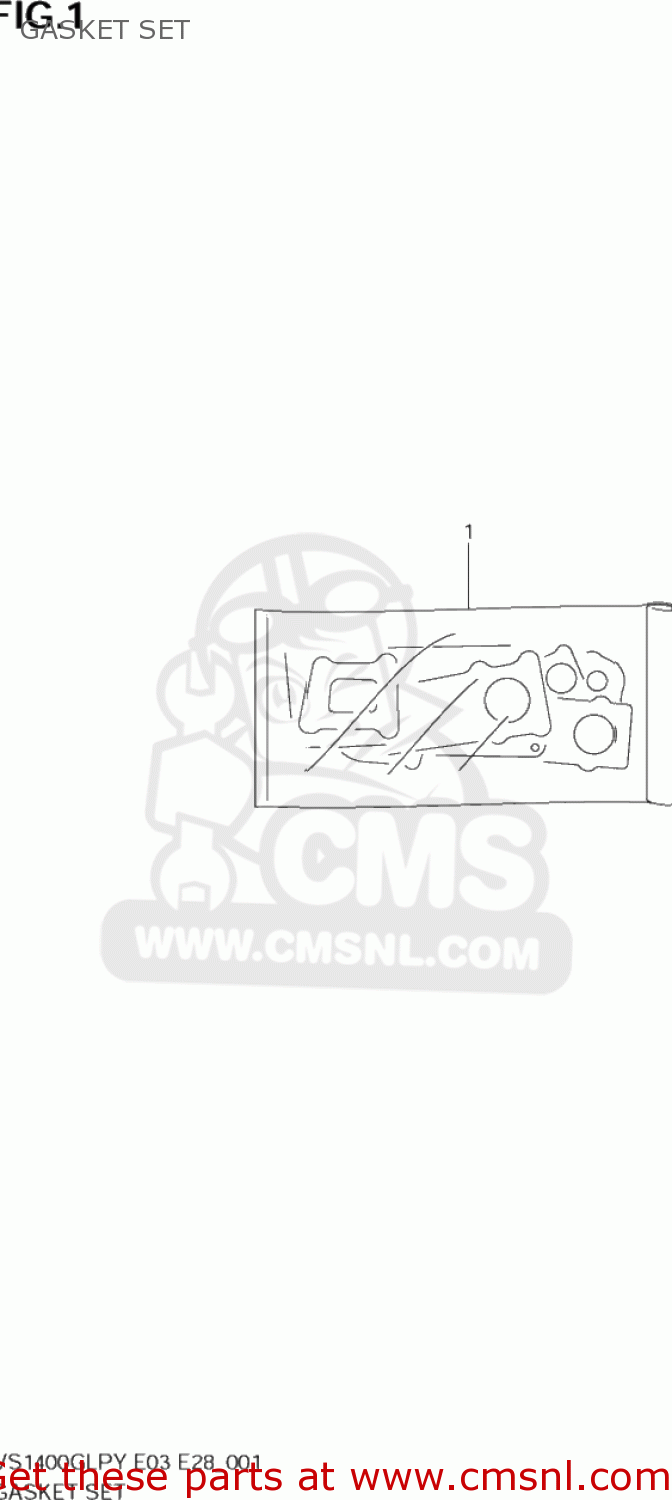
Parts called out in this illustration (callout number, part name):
1	GASKET SET (NAS)
2	GASKET,CYLINDER HEAD FR (NAS)
3	GASKET,CYLINDER HEAD RR (NAS)
4	GASKET,BREATHER COVER (NAS)
5	GASKET,CYLINDER FR (NAS)
6	GASKET,CYLINDER RR (NAS)
7	GASKET,CLUTCH COVER (NAS)
8	GASKET,GENERATOR COVER (NAS)
9	GASKET,GEAR SHIFT COVER (NAS)
10	GASKET,EXHAUST PIPE (NAS)
11	GASKET(6.2X13X1.2) (NAS)
12	GASKET(5.8X13X1.2) (NAS)
13	GASKET(8.2X14X1).6 (NAS)
14	GASKET(14X19.2X2) (NAS)
15	GASKET(14X20X1.5) (NAS)
16	GASKET(16X22X2) (NAS)
17	GASKET(16X22X2) (NAS)
18	GASKET(18X24.2X2) (NAS)
19	O RING(D:1.2,ID:4)
20	O RING(D:1.9,ID:12.6)
21	O RING(D:3.1,ID:16.8)
22	O RING(D:3.1,ID:22.7)
23	O RING(D:2.4,ID:36.5)
24	O-RING (D:1.9 ID:40.7)
25	O RING(D:2.4,ID:41.7)
26	O RING(D:3.7,ID:76.5)
